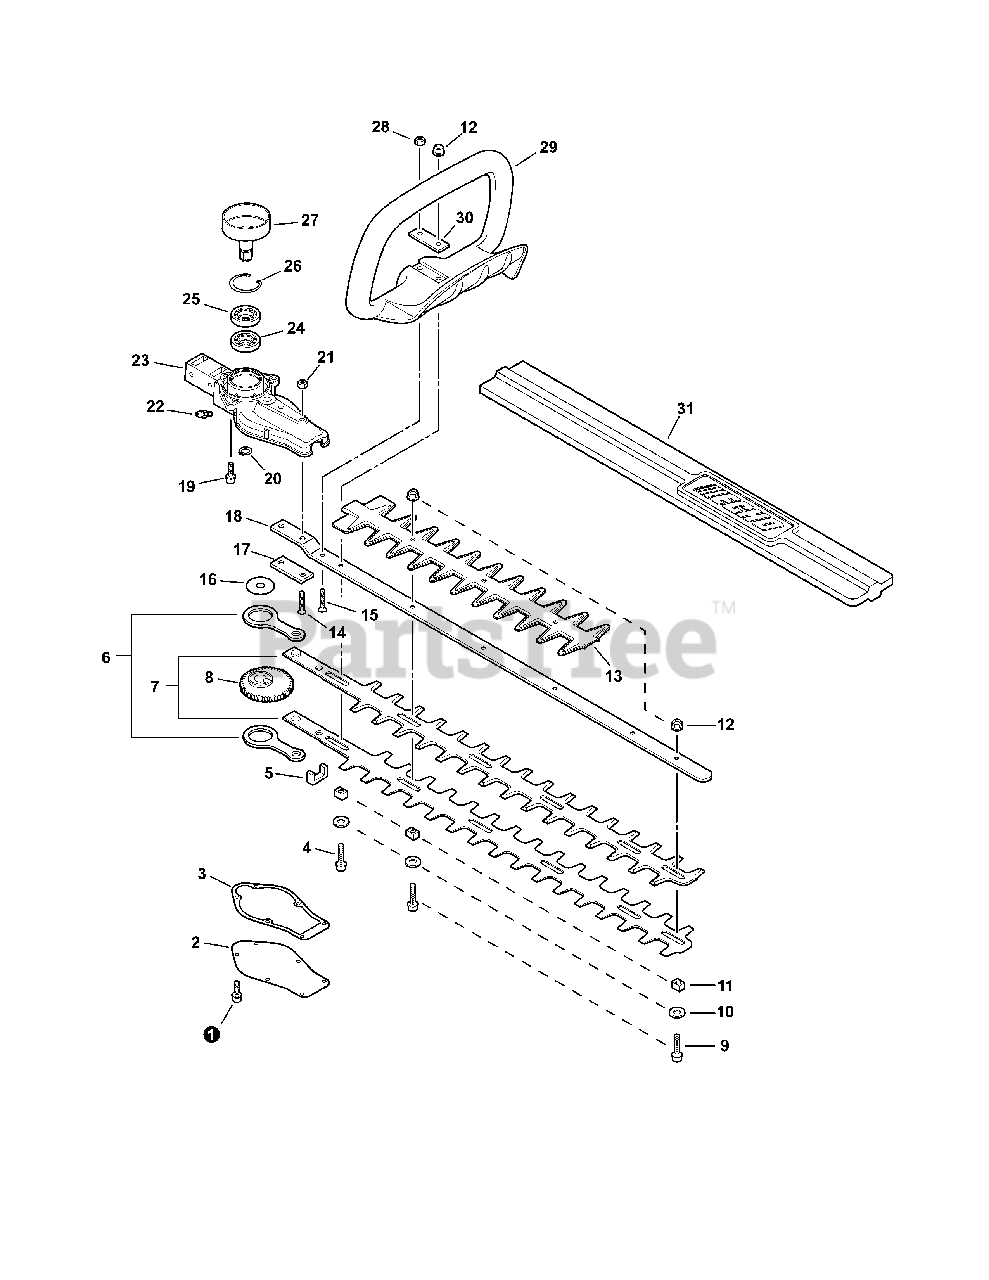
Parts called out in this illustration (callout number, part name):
1	SCREW - 4×10
2	LID, GEAR CASE
3	GASKET, GEAR CASE
4	SCREW - 5×40
5	SEAL, FELT
6	ROD, CONNECTING
7	BLADE, TRIMMER - 20"
8	GEAR - DRIVE
9	SCREW - 5×20
10	WASHER - 6
11	GUIDE, BLADE
12	LOCKNUT - 5
13	PROTECTOR, BLADE
14	SCREW - 6×25
15	SCREW - 5×30
18	SUPPORT, BLADE
19	SCREW - 5×20
20	RING, RETAINING - 14
21	LOCKNUT - 6
22	FITTING, GREASE
23	CASE, GEAR
24	BEARING, BALL - 6202
25	BEARING, BALL - 6202
26	RING, RETAINING - 35
27	DRUM, CLUTCH
28	LOCKNUT - 5
29	HANDLE - FRONT
31	COVER, BLADE - 20" (50cm)
